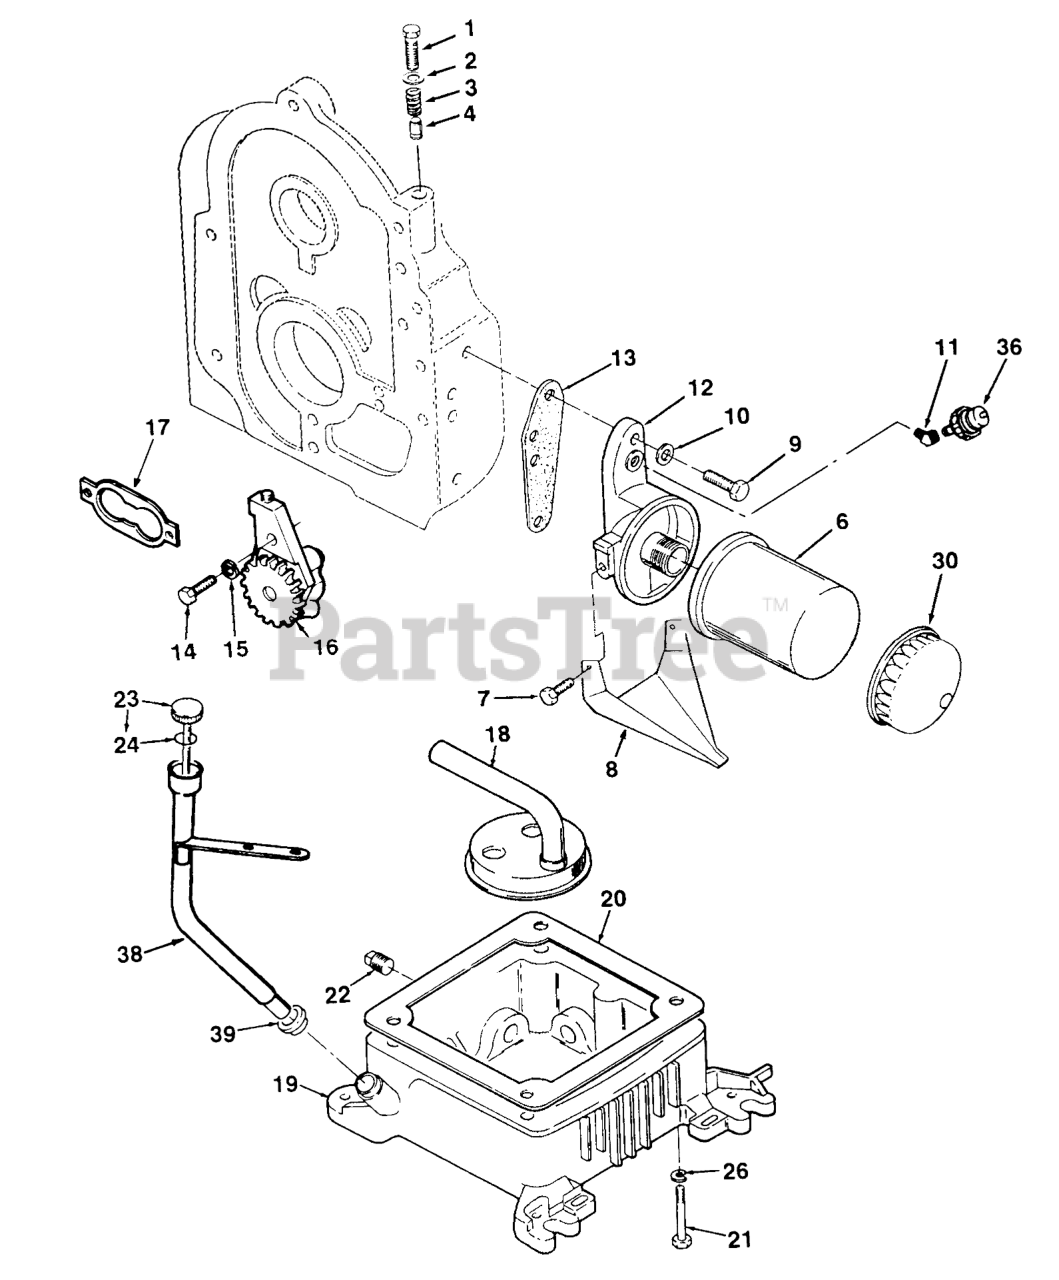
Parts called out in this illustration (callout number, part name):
1	HX HD CAPSCREW
2	WASHER
3	SPRING
4	PLUNGER
6	FILTER-OIL
7	SCREW-HH
8	DRAIN-OIL FILTER
9	HHCS 5/16-18 X 1
10	WASHER
11	ELBOW-45 DEG
12	ADAPTER-OIL FILTER
13	Gasket
14	SCREW - CAP HEX HEAD
15	WASHER-FLAT
17	GASKET KIT
18	CUP-OIL PUMP INTAKE
19	Base-Oil (Incl. Plugs)
20	GASKET
21	SCREW-HH
23	Oil Fill Cap & Indicator (Incl. O-Ring)
24	SEAL 0-RING
26	WASHER-FLAT
30	WRENCH-OIL FILTER
36	OIL-PRESSURE SWITCH
38	TUBE-OIL FILTER
39	SEAL-OIL FILL TUBE
